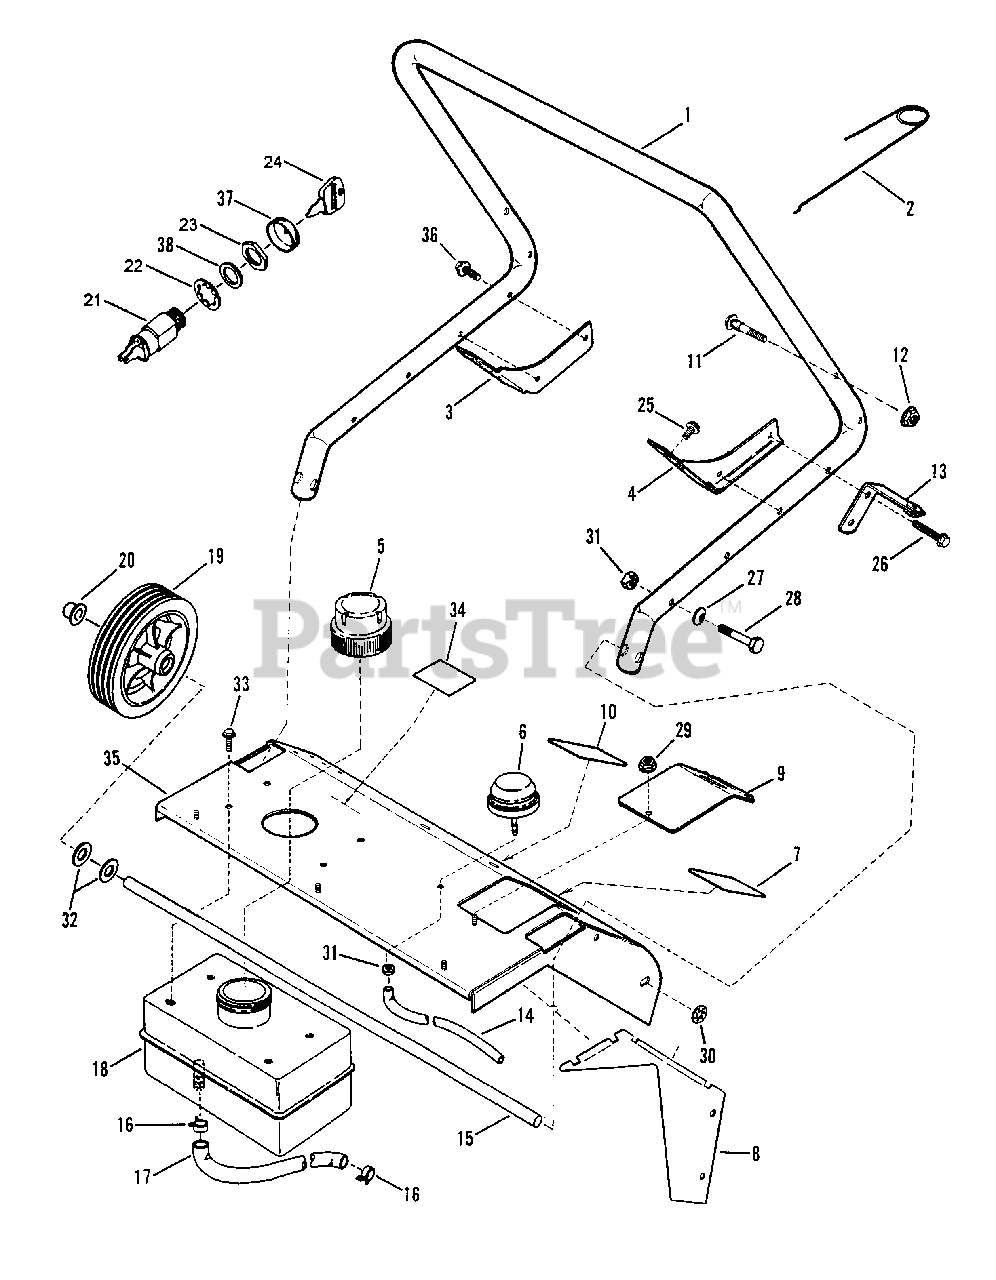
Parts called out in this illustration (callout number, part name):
1	HANDLE, Lower
2	CONTROL, Choke
3	HANDLE, Brace (Right Hand)
4	HANDLE, Brace (Left Hand)
5	CAP, Fuel Tank
6	PRIMER, Fuel
7	DECAL, Choke
8	BAFFLE, Left Hand
9	COVER, Access Hole
10	DECAL, Controls
11	BOLT, 1/4-20 x 1-3/8" Carriage, Grade 5
12	NUT, 1/4-20 Hex Flange Lock
13	ASSEMBLY, Bracket & Bushing
14	HOSE, Primer
15	AXLE
16	CLAMP, Fuel Line
17	LINE, Fuel
18	TANK, Fuel
20	NUT, 3/8 Push
21	SWITCH, Ignition
22	WASHER, 5/8 Internal Tooth Lock
23	NUT, 5/8-32 Hex (Special)
24	KEY, Ignition
25	SCREW, 010-32 x 1/4" Self-Tapping
26	SCREW, 1/4-20 x 1-3/8" Self-Tapping
27	WASHER, 1/4 Curved
28	SCREW, 1/4-20 x 1-1/4" Hex Head Cap (Gr. 5)
29	NUT, #10-24 Hex Flange Lock
30	RETAINER, 1/4 Bolt
31	NUT, 1/4-20 Hex Center Lock
32	WASHER, 3/8" Flat
33	SCREW, 1/4-15X3/4, Self-Tapping, BZ
34	DECAL, Fuel Mix Chart
35	WELDMENT, Handle/Panel
36	SCREW, 1/4-20 1-1/4" Self-Tapping
37	BEZEL
38	SPACER
